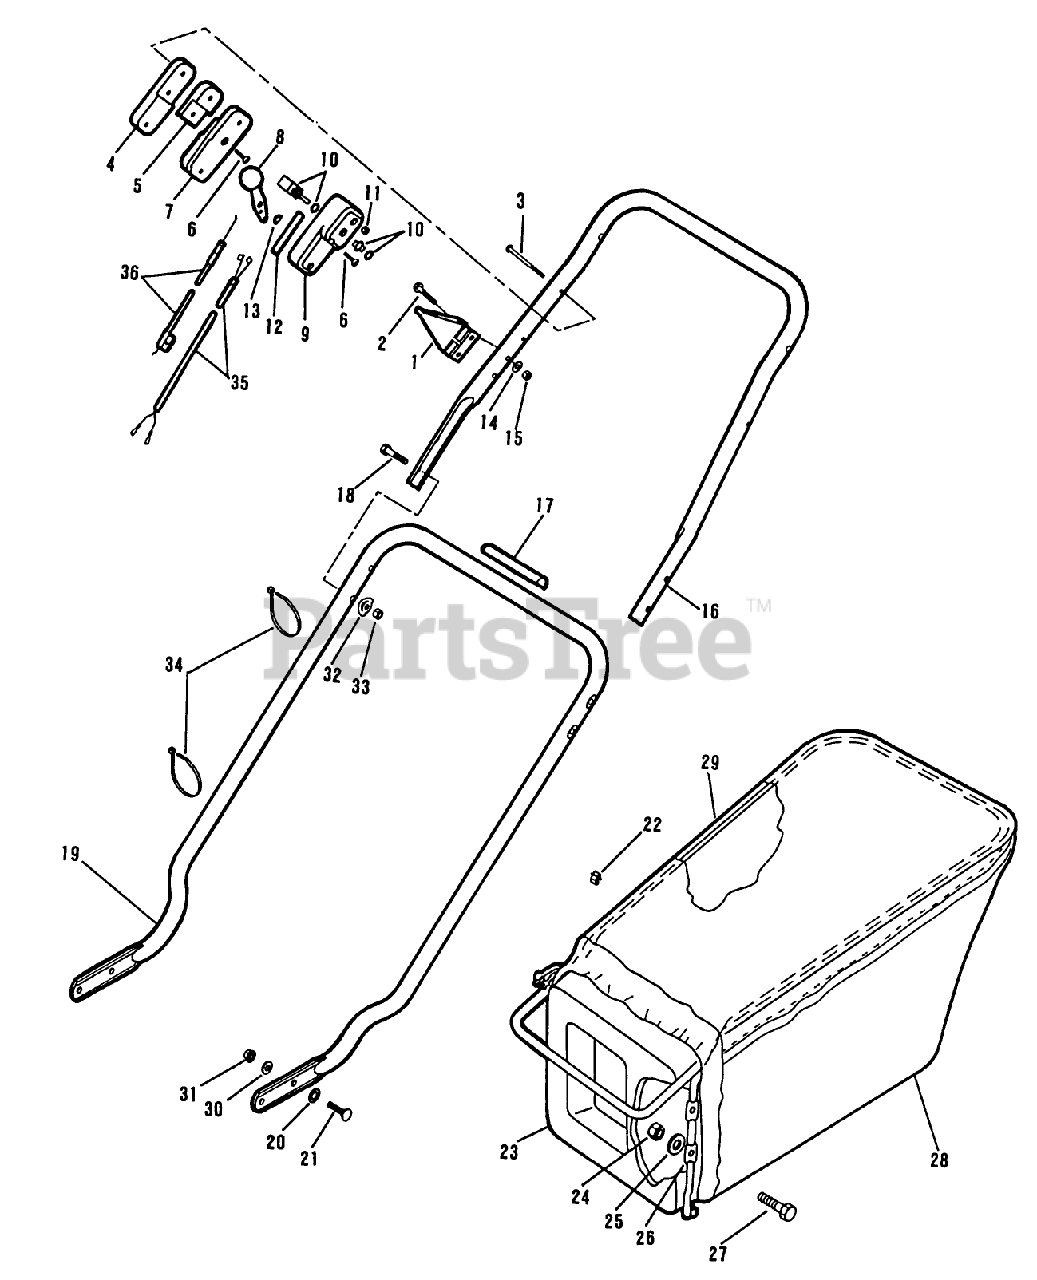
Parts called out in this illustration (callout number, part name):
3	SCREW
4	OUTER CONTROL CASE
6	SCREW
8	LEVER&KNOB AY WES
11	NUT C/LOCK E
13	WASHER-SPRING
14	WASHER
15	LOCKNUT E
16	UPPER HANDLE *
19	LOWER HANDLE *G
22	S CLIP ARDEN
23	BAG ADAPTOR PL
24	LOCKNUT E
25	WASHER
26	LATCH BAR AY ARGO
29	HANGER BAG TROX
30	WASHER
32	WASHER-CURVED
33	NUT-LOCK F
36	THROTTLE CABLE
